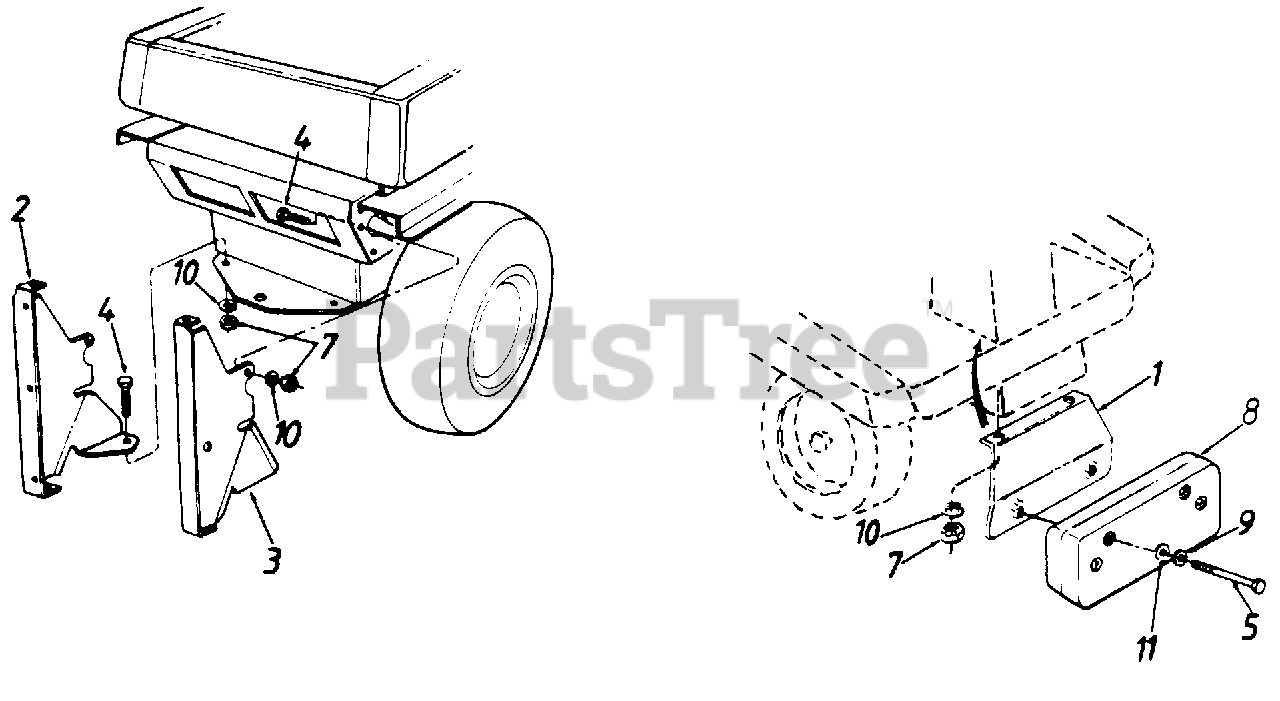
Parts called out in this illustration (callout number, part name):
1	Counteneight Support Brkt.
2	Catcher Support Brkt. R.H.
3	Catcher Support Brkt. L.H.
4	Hex Bolt 5/16-18 x l.00 Lg.
5	Hex Bolt 3/8-16 x 4.5" Lg.
7	Hex Nut 5/16-18 Thd.
8	Front Counterweight
9	Bell-Wash. 818" I.D.
10	L-Wash. 5/16" I.D.
11	Fl-Wash. .390" I.D. x l.12" O.D.
